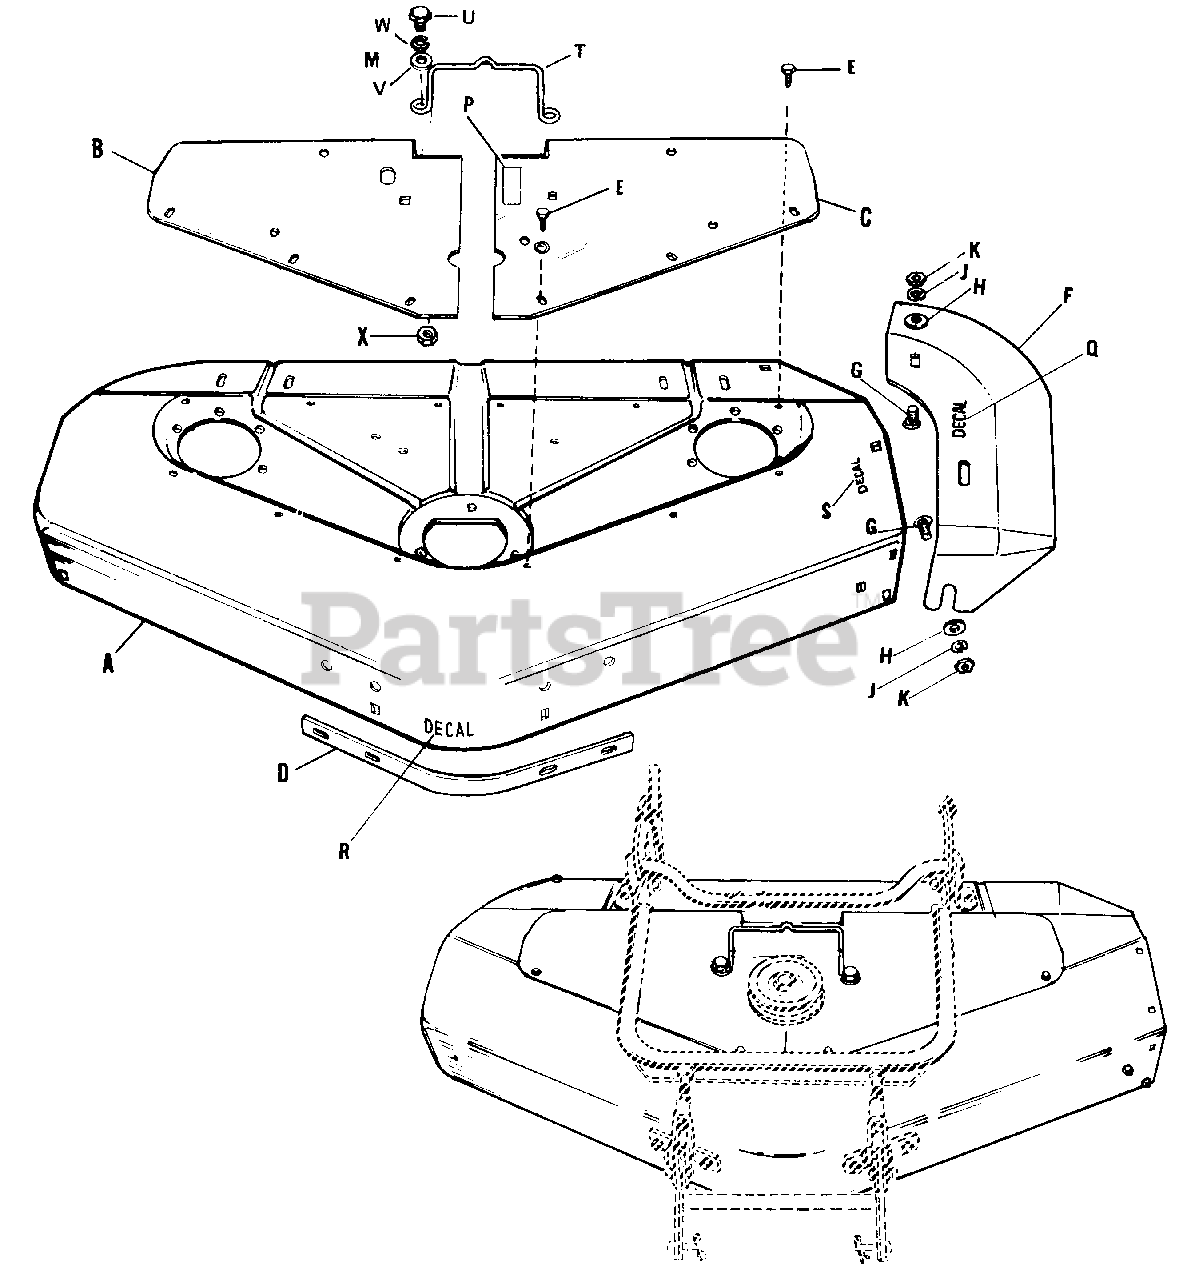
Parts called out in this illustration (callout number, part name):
A	Mower Housing
B	Cover, R.H.
C	Cover, L.H.
D	Bar, Reinforcing
E	Screw, Taptite, 1/4-20 x 3/8" lg.
F	Deflector
G	Carriage Bolt, 3/8"-16 x 3/4" lg.
H	Washer-Special
J	Washer, Lock, 3/8"
K	Hex Nut, Full, 3/8-16
P	Film-Belt Instructions
S	Film, Safety
T	Belt Guide Assembly
U	Hex Cap Screw 5/16"-18 x 7/8"
V	Plain Washer 5/16
W	Lock Washer, 5/16
X	Nut Retainer
